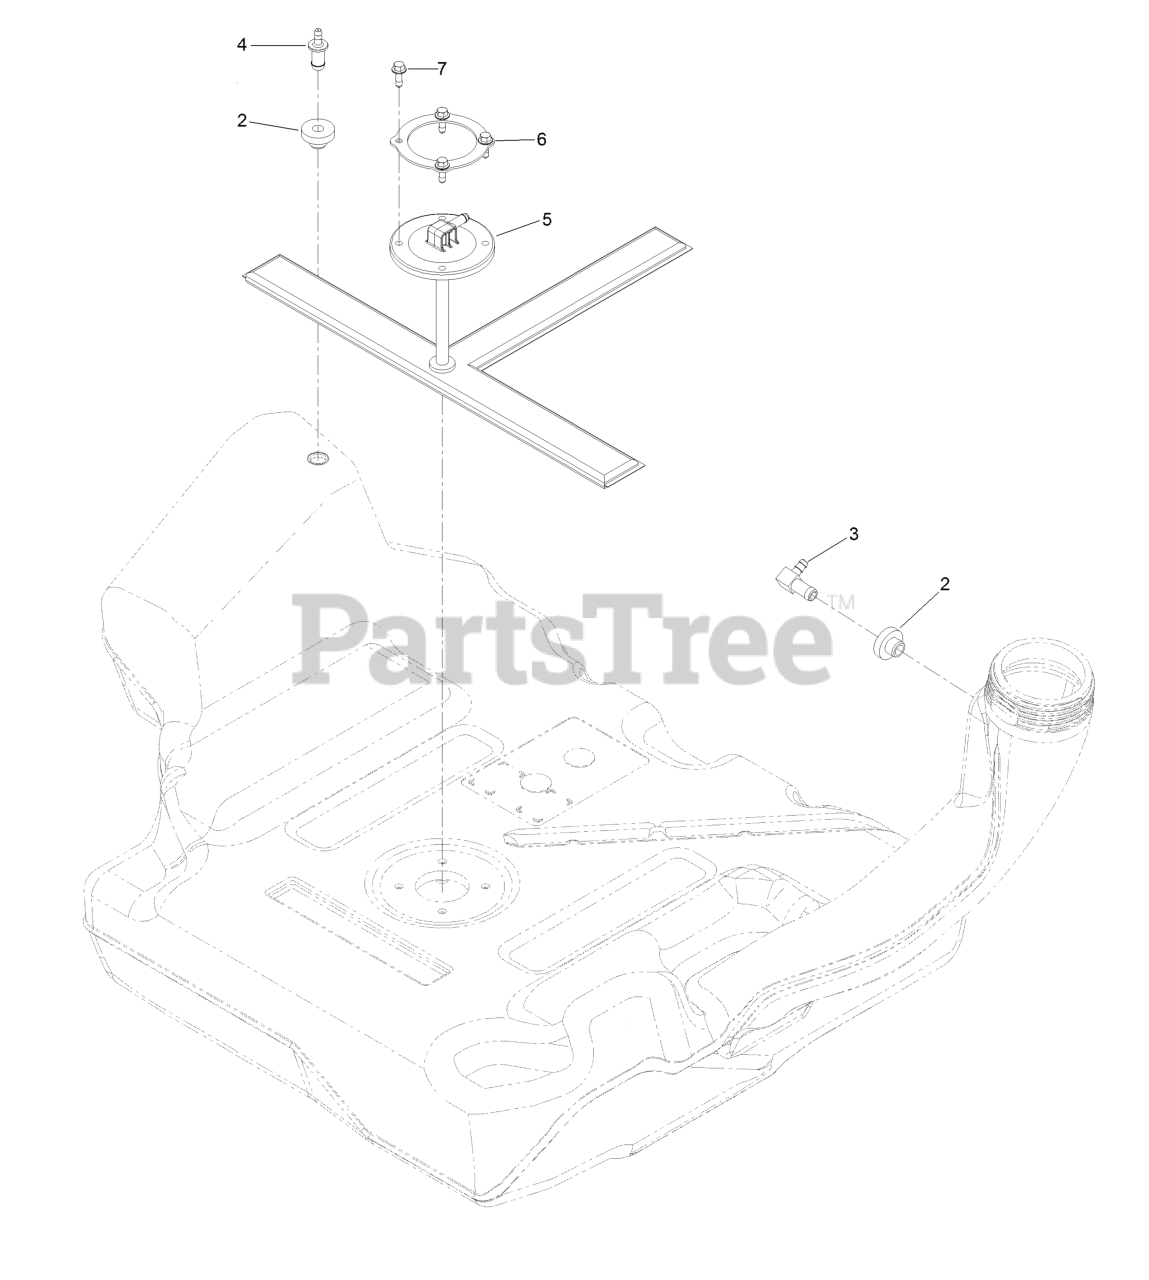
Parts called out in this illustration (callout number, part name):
2	Bushing
3	Fitting-90 DEG
4	Fitting-Orifice, Straight
5	Pickup-Fuel
6	Ring-Retainer
